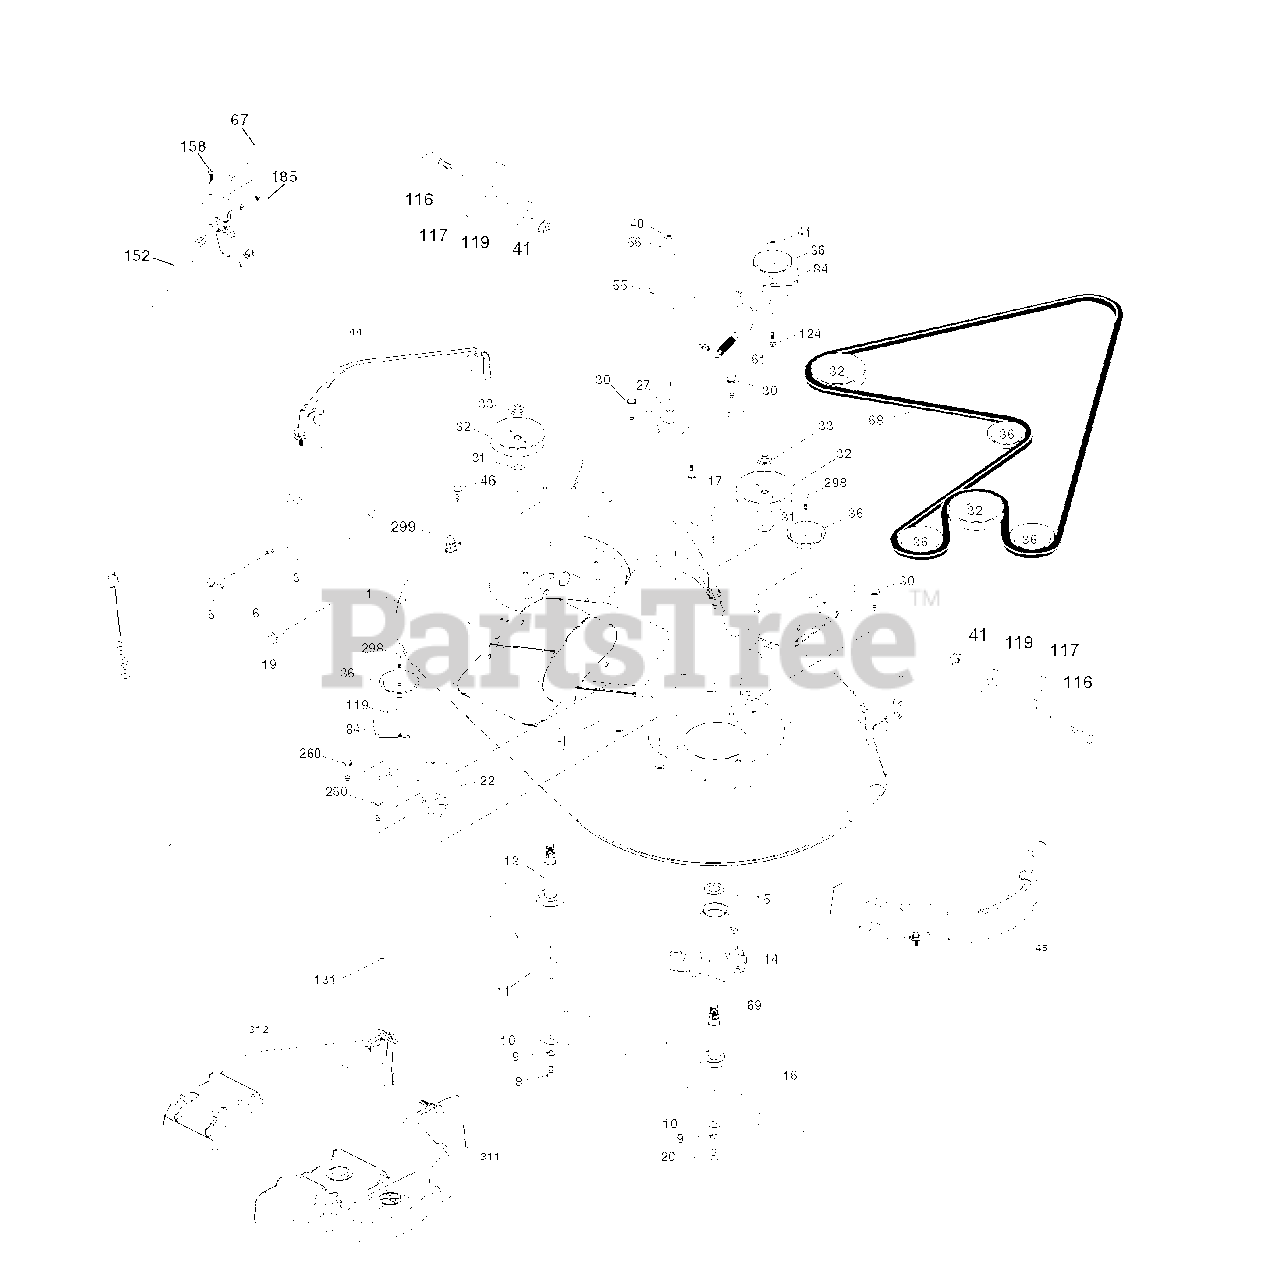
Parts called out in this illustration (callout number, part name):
3	BRACKET.ASM.BAR.SWAY.CHASS
5	RETAINER-SPRNG RB
6	BAR SWAY
9	LOCKWASHER
10	WASHER.BLADE
11	BLADE.3N1.LH.CRD.97
13	SHAFT ASM VENT
14	HSG MANDREL
16	BLADE.3N1.RH.CRD.97
17	BOLT.3/8-14X1.25
19	BOLT SHD 5/16-18
22	BRACKET.SUPT.IDLER.REAR.RH
27	BRACKET.ASM.SUSP.REAR.RH.
30	SCREW, WASHER HEAD
31	WASHER.SPACER.MANDREL
32	PULLEY MANDREL
33	NUT.FLANGE.LOCK.TOP
36	PULLEY.IDLER.4.25
40	LOCKNUT
41	NUT LOCK FLG 3/8-16 UNC
46	SCREW.1/4-20X5/8
56	SPACER.RETAINER.MOWER
67	KNOB T (3/8 HOLE)
68	BELT.DRIVE.CRD.97.2010
69	SHAFT.ASM.W/LWR.BRG.RH.THREAD
84	KEEPER, BELT IDLER
116	BOLT.SHOULDER.3/8-16X3-5/8
117	WHEEL. GUAGE RALLY
124	BOLT.3/8-16X1.50
131	CHUTE BAGGER
158	SCREW
185	HEAD ASM. CABLE CLUTCH
260	SCREW 3/8-16X1/2
298	SCREW LT
299	PORT.WASHOUT
